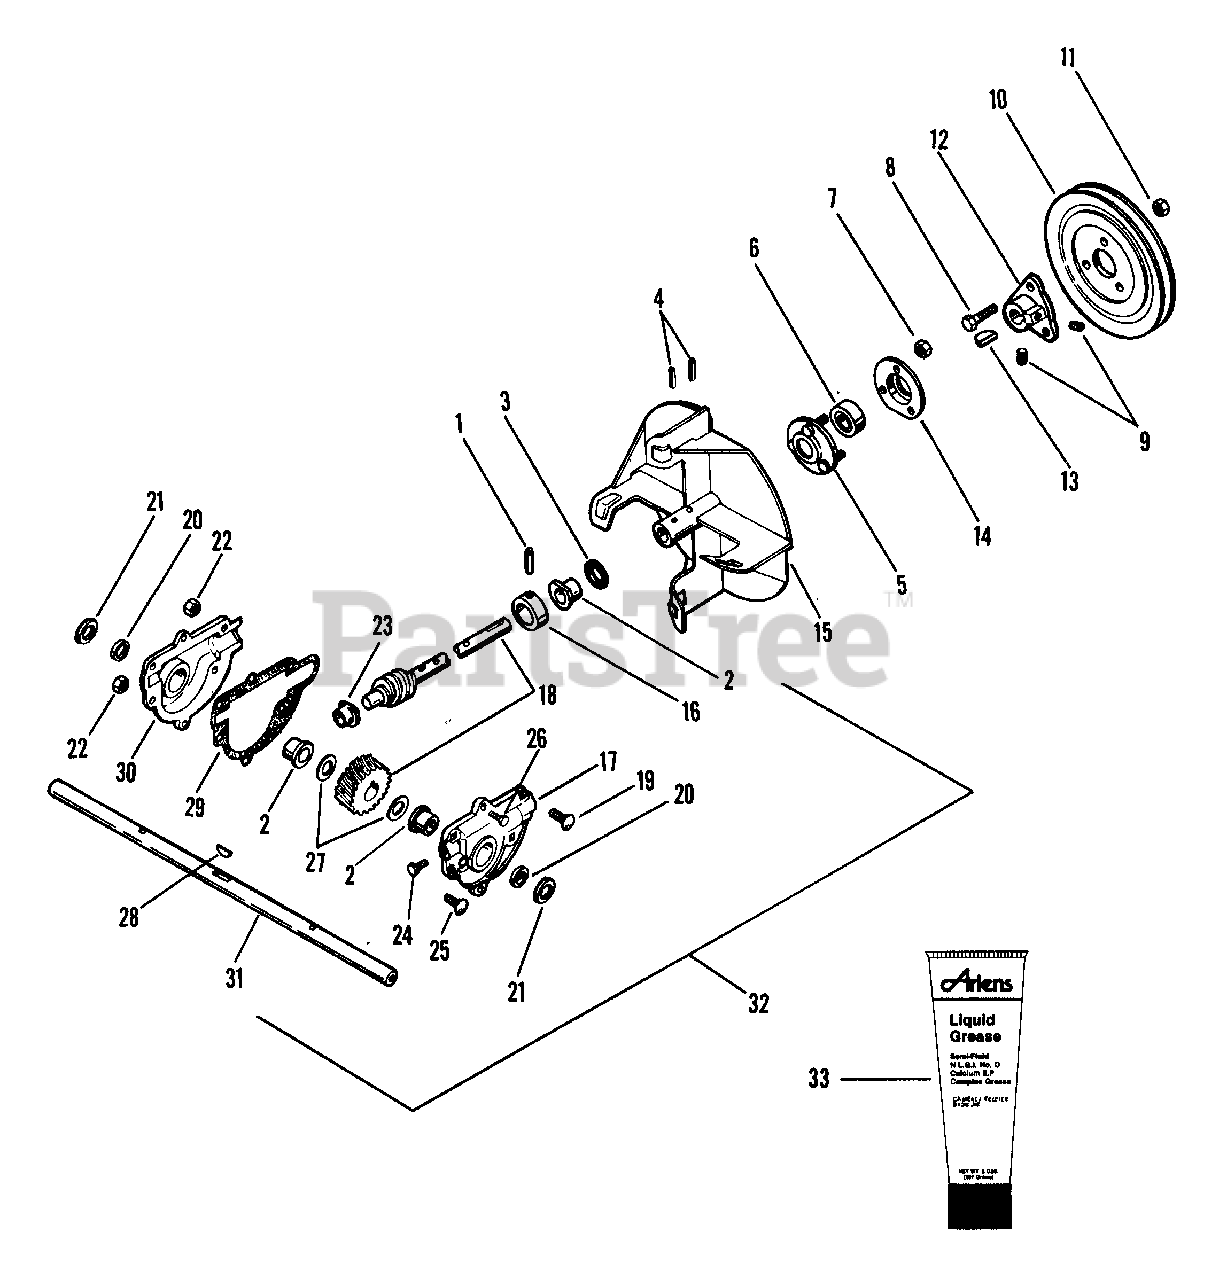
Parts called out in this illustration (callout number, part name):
1	PIN-GRV .188X1.25 TP A
2	BSHG-FLG .750X1.000X.750X1.250
3	O-RING .250X.943X.103
4	PIN-ROLL .250X1.25
5	BEARING FLANGE
6	BRG-BALL .750X1.750X.50
7	NUT-LK-CTR .250-20 PL
8	BLT-SERRDHD SL .31-18X.75 YZ
9	SCR-SET .32-18X.38 SKHCUPNL OH
10	PLY-V 7.0 X 1.25 3BLT
11	NUT-FLG. .312-18 PL
12	HUB
13	KEY-WDRF .188X.875X.375 SAE11
14	BEARING FLANGE
15	IMPELLER - 10"
16	THRUST COLLAR
17	L H GEAR CASE HALF
18	SHAFT AND WORM GEAR ASSEMBLY
19	BLT-RDHDSQNK .25-20X1.25 GR5PL
20	SEAL .750X1.000X.125
21	WSHR-FL-STL.812X1.500X.139
22	NUT-LK-FLG .250-20 PL
23	BSHG-FLG .500X.750X.750X1.000
24	SCR-TAP .375-16X .50 HWH PL TR
25	BLT-RDHDSQNK .25-20X.88 PL
26	SCR-TAP 10-24X.75 HWH PL TR
27	WSHR-HDND-THRST .755X1.40X.062
28	KEY-WDRF .188X.625X.25 SAE 61
30	R H GEAR CASE HALF
31	SHAFT, RAKE - 20"
31	SHAFT, RAKE - 24"
32	GEAR CASE - 20" - ALUMINUM
32	GEAR CASE - 24" - ALUMINUM
33	8 OZ TUBE OF LIQUID GREASE
